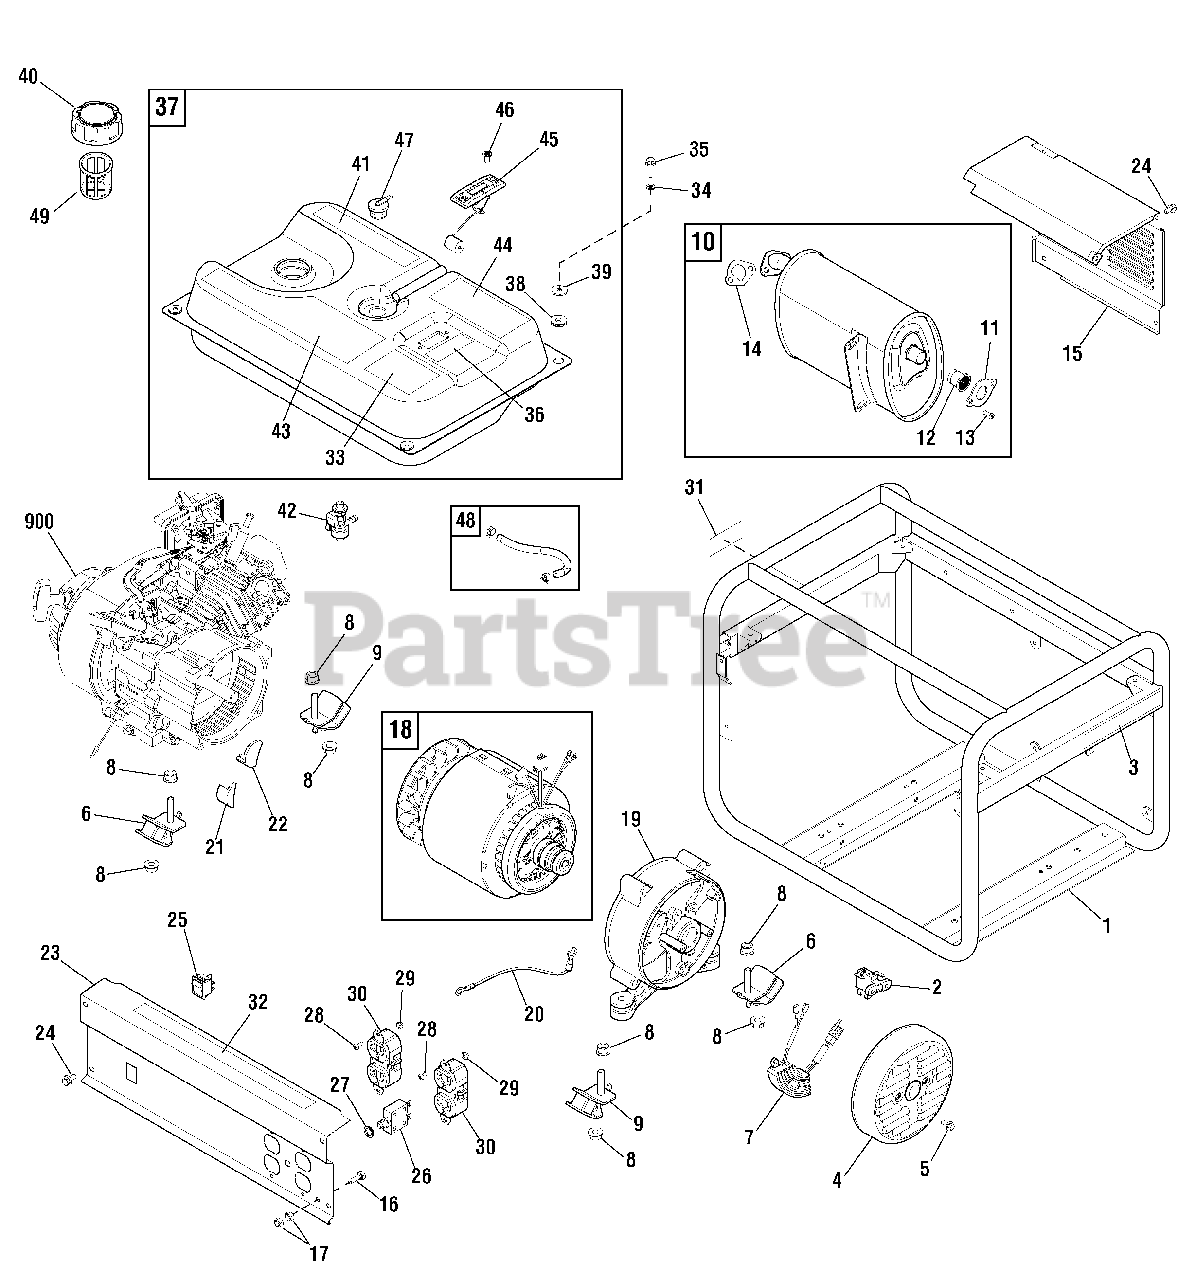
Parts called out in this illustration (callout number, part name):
5	* BOLT, M5 x 12
6	MOUNT-VIBRATION
7	VOLTAGE REGULATOR
8	* NUT, Flange, M8
9	MOUNT-VIBRATION
12	SPARK ARRESTOR
13	* SCREW, M5 x 12
14	GASKET-MUFFLER
15	COVER-MUFFLER
16	* BOLT, M5 x 16
17	* NUT, M5
19	CARRIER-BEARING
23	PANEL-CONTROL
24	* BOLT, M6 x 12
26	BREAKER-CIRCUIT
28	* SCREW, M4 x 14
29	* NUT, Flange, M4
34	* WASHER, Lock, M6
35	* BOLT, M6 x 20
38	MOUNT-VIBRATION
46	* SCREW, M5 x 10
48	KIT-FUEL HOSE
900	** ENGINE
